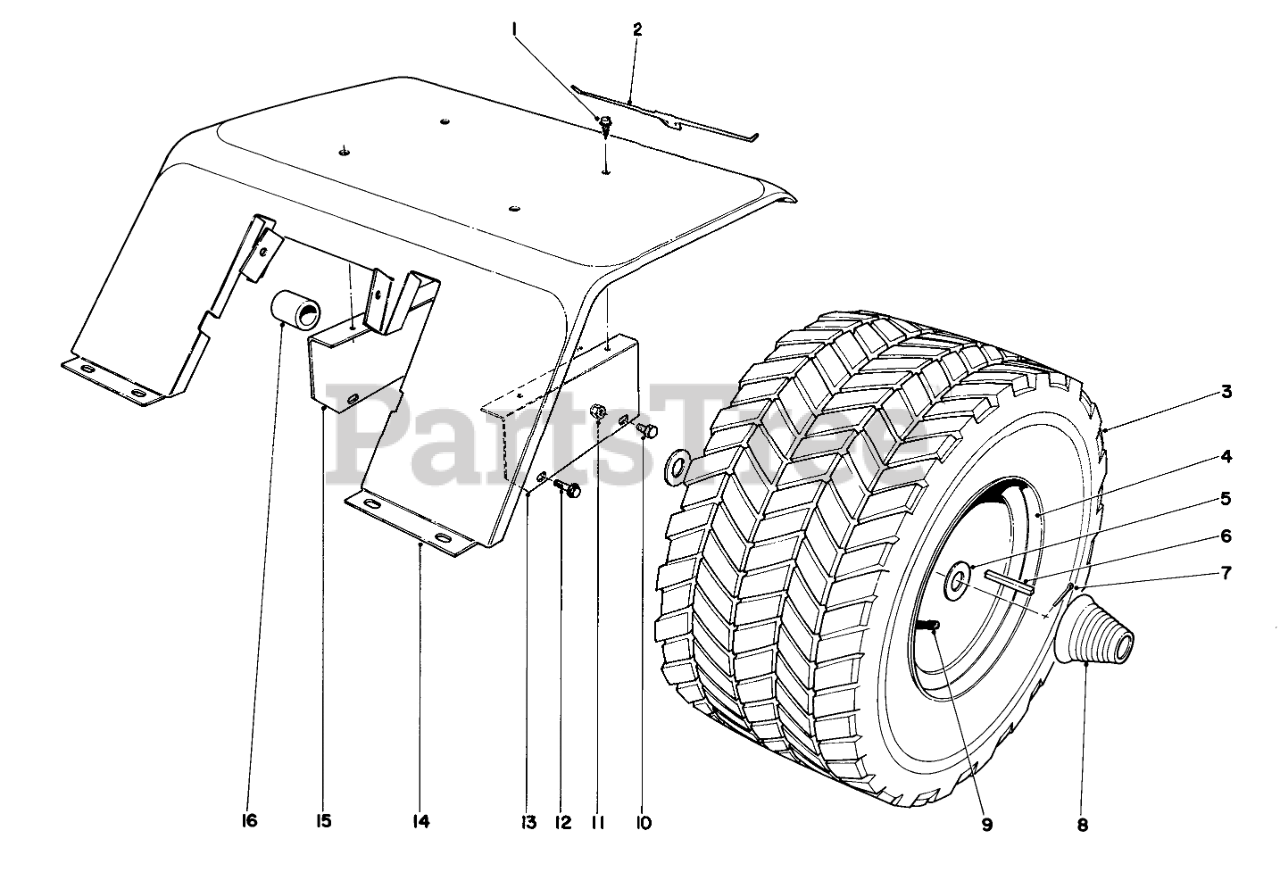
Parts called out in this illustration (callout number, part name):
1	SCREW-HWH
2	Decal
5	Washer
6	KEY-CLUTCH
7	PIN-COTTER
8	Hub Cap
9	VALVE -STEM
10	SCREW-HH
11	NUT-LOCK, CONE
12	1/4-20X5/8 THDG SEMS
13	Fender Support L.H.
14	Fender
15	Fender Support R.H.
16	Spacer
